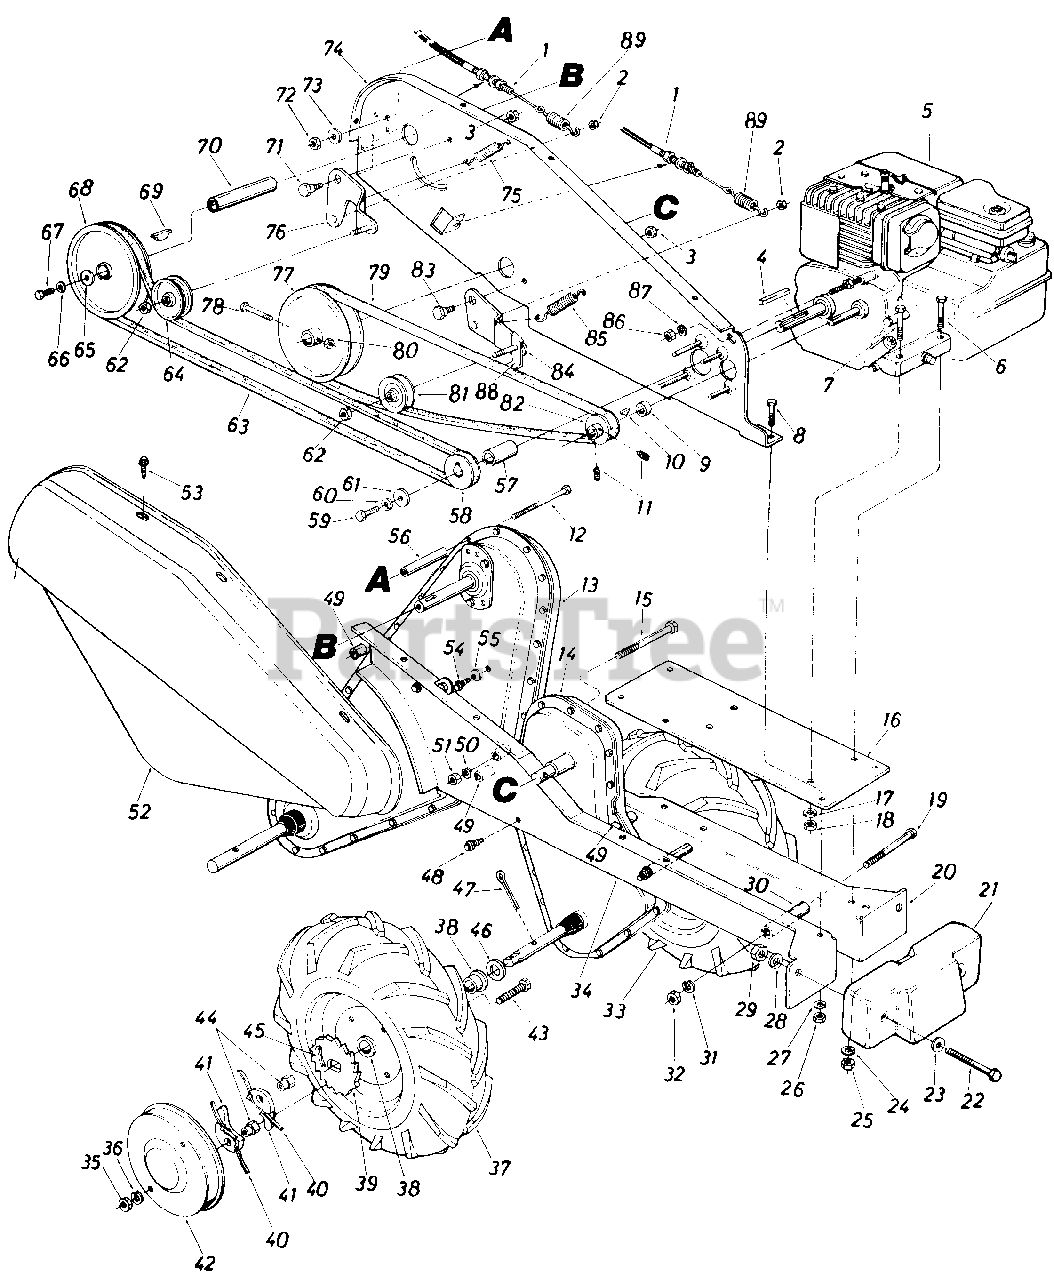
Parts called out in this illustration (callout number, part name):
1	Clutch Control Cable
2	Hex Cent. L-Nut 1/4-20 Thd.
3	Hex Cent. L-Nut 3/8-16 Thd.
4	Sq. Key 3/16" Dia. x .75
5	Engine
6	Hex Bolt 5/16-18 x 1.50" Lg.
7	Hex Bolt 5/16-18 x 1.50" Lg.
8	Hex Bolt 5/16-18 x .75" Lg.
9	Spacer .51" I.D. x 3/4" O.D. x .39" Lg.
10	Hi-Pro Key #5 Woodruff
11	Set Scr. 1/4-28 x .25" Lg.
12	Hex Bolt 5/16-18 x 3.0" Lg.
15	Hex Bolt 5/16-18 x 3.0" Lg.
18	Hex Nut 5/16-18 Thd.
19	Hex Bolt 3/8-24 x 3.0" Lg.
22	Hex Bolt 1/2-13 x 4.0" Lg.
23	Fl-Wash. 1/2 I.D. x 1.0" O.D.
24	L-Wash. 5/16" I.D.
25	Hex Nut 5/16-18 Thd.
26	Hex Nut 5/16-18 Thd.
27	L-Wash. 5/16" I.D.
28	L-Wash. 1/2" I.D.
29	Hex Nut 1/2-13 Thd.
30	Spacer 3/8" I.D. x 5/8" O.D. x 2.18" Lg.
31	L-Wash. 3/8" I.D.
32	Hex Nut 3/8-24 Thd.
33	Comp. Wheel Ass'y. - L.H.
36	L-Wash. 5/16" I.D.
37	Comp. Wheel Ass'y. - R.H.
38	Flange Brg. 7/8" I.D. x 1.12" Lg.
39	Ratchet Wheel
40	Nylon Spring
41	Pawl .44" I.D.
42	Wheel Cover
43	Hex Bolt 5/16-24 x 1.25" Lg.
44	Special Hex Nut 5/16-24 Thd.
45	Cotter Pin 1/8" Dia. x 1.25" Lg.
46	Fl-Wash. 7/8" I.D. x 1-3/8" O.D. x .06
47	Cotter Pin 1/8" Dia. x 1.25" Lg.
48	Hex Wash. Self-Tap Scr. 5/16-24 x .50" Lg.
49	Spacer 5/16" I.D. x 16 Ga. x .96" Lg.
50	L-Wash. 5/16" I.D.
51	Hex Nut 5/16-18 Thd.
52	Belt Cover
53	Hex Wash. S-Tap Scr. 1/4-20 x .50" Lg.
54	Hex Wash. S-Tap Scr. x 3/8" Lg.
55	Bell-Wash. 1/4" I.D.
56	Spacer 3/8" I.D. x 1/2" O.D. x 2.0" Lg.
57	Spacer 3/4" I.D. x 1.12" O.D. x 1.56" Lg
58	1/2" "V"-4L Pulley 3/4" I.D. x 2.59" O.D.
59	Hex Bolt 5/16-24 x 1.00" Lg.
60	L-Wash. 5/16" I.D.
61	Fl-Wash. 5/16" I.D. x 1.25" O.D.
62	Hex L-Nut 3/8-24 Thd.
63	"V"-Belt 1/2" x 54" Lg.
64	Fl-Idler Pulley 3.75" O.D. x 3/8" I.D.
65	Fl-Wash. .25" I.D. x .93" O.D. x .120
66	L-Wash. 1/4" I.D.
67	Hex Bolt 1/4-28 x .75" Lg.
68	Split Pulley 6" Dia. x 5/8" I.D
69	Hi-Pro Key
71	Shld. Bolt 1/2" Dia. x .210" Lg.
72	Hex Nut 5/16-18 Thd.
73	Bell-Wash. 5/16" I.D.
74	Side Plate Ass'y.
75	Ext. Spring .50" O.D. x 1.55" Lg.
76	Idler Bracket Ass'y. - Tines
77	Pulley 6" Dia. x 5/8" I.D.
78	Hex Bolt 1/4-28 x 1.50" Lg.
79	"V"-Belt 1/2" x 43" Lg.
80	Hex Cent. L.-Nut 1/4-28 Thd.
81	"V"-Idler Pulley 2-5/8" O.D.
82	1/2" "V"-Pulley 2 1/4" O.D. x .50" I.D.
83	Shld. Bolt 1/2" Dia. x .160" Lg.
84	Idler Bracket Ass'y - Wheels
85	Ext. Spring .50" O.D. x 1.97" Lg.
86	Hex Nut 1/4-20 Thd.
87	L-Wash. 1/4 I.D.
88	Belt Keeper Ass'y.
89	Ext. Spring
